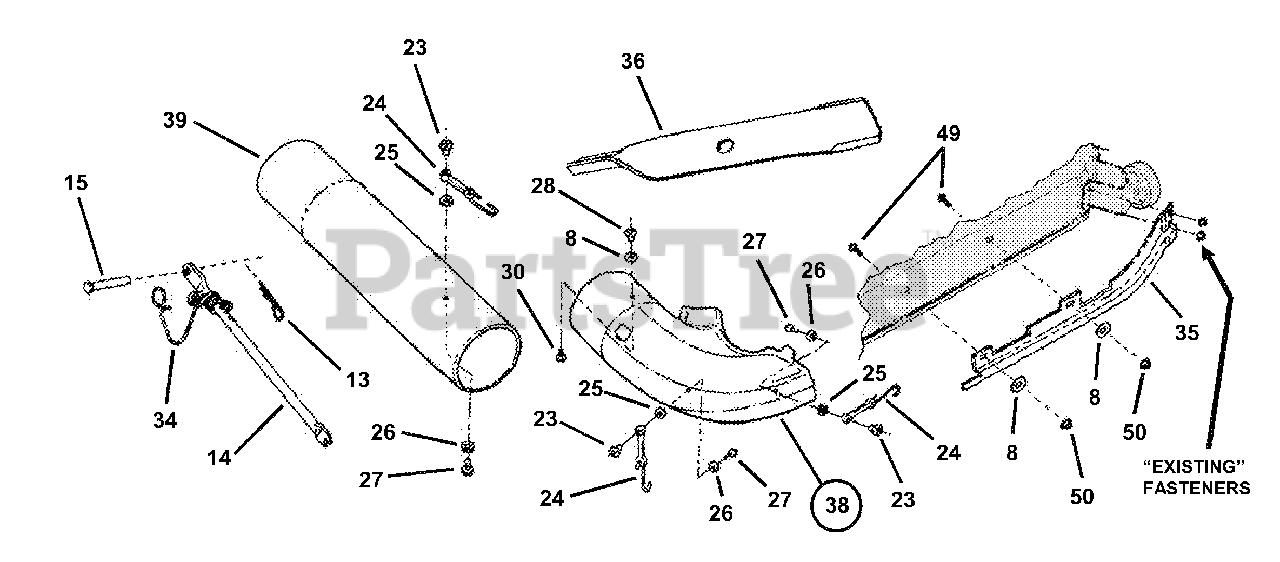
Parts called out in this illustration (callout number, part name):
8	WASHER, 11/32" Flat
13	PIN, 3/32 x 1-1/2" Hair
14	BRACE, Rear
15	PIN, 5/16 x 1-11/16" Clevis
23	NUT, #10-24 x 5/8" Weld
24	STRAP, Adapter/Tube
25	WASHER, 3/16" Flat
26	WASHER, 7/32" Flat
27	SCREW, #10-24 x 5/8" Pan Hd.
28	TEENUT, 5/16-18
30	SCREW, 5/16-18 x 5/8" Mach.
34	ASS'Y, Spring & Hook
35	BAFFLE, 38" Deck
36	ASSEMBLY , High Lift Blade & Decal #44686 blade length 19.64"; blade hole diameter .981"
38	ADAPTER,
39	TUBE, Grass (37" long)
49	SCREW, 5/16-18 x 3/4" Cap
50	NUT, 5/16-18 Hex Ctr. Lock
